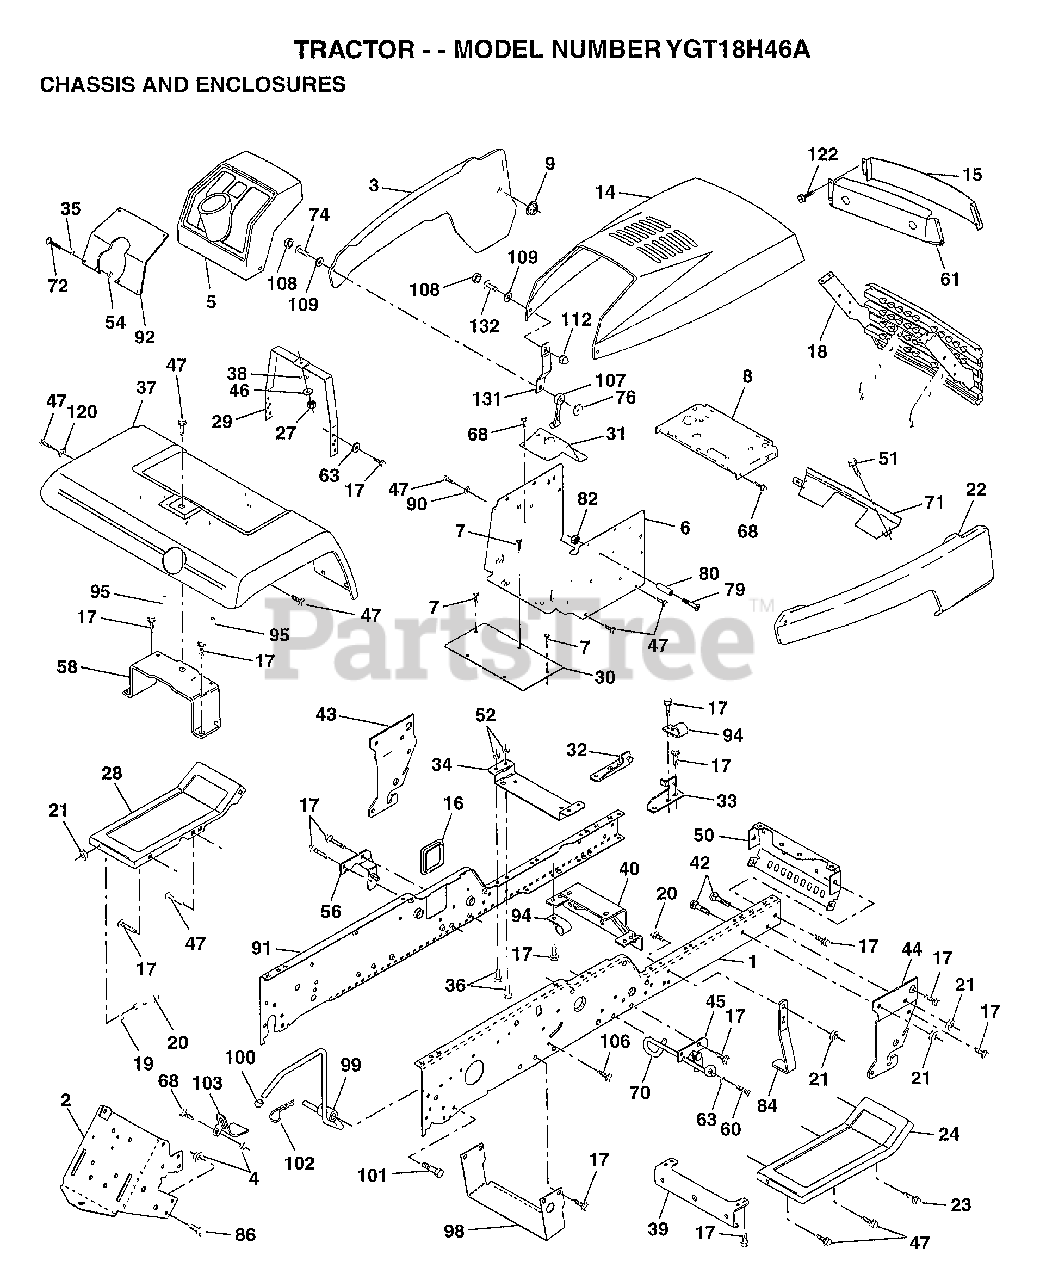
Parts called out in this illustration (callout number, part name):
1	"RAIL,FRAME RH"
2	DRAWBAR GT
3	"PANEL ASM-SIDE,LH"
4	NUT.7/16
5	DASHBOARD BLACK
6	DASH LOWER
7	SCREW
8	SUPPORT.DASH.BTRY
9	PAL NUT LT
14	"HOOD, YARD PRO"
15	LENS.BAR.CLEAR
16	COVER ACCESS
17	SCREW
19	WASHER
20	BOLT
22	"PANEL ASM SIDE,RH"
23	SCREW GTV
24	FOOTREST.RH.LT/GT
28	FOOTREST PNT LH
29	DASH.SUPT.YP/HUSQ
30	SADDLE.HYDRO.95
31	BRAKET.SUPT.STEER
32	BRACKET ASM FRAME
33	BRACKET ASM FRAME
34	BRACKET.ENG.SUPT.
35	WASHER
36	BOLT
37	"FENDER WS,FTK"
38	LOCKWASHER
39	BRACKET.AXLE.FRT.
40	"BRKT SUPPORT,AXLE"
43	BRACKET.SUS.FT.LH
44	BRACKET.SUS.FT.RH
45	BRACKET ASM., SUSP CHASSIS RH
46	WASHER PM
47	SCREW LT
50	"BRKT CHASSIS,FRNT"
51	SCREW CRT
56	BRACKET ASM., SUSP CHASSIS LH
58	BRKT.ASM.FENDER
60	SCREW
61	BEZEL.ASM.
63	WASHER
68	SCREW LT
70	GUIDE.BELT.MID.SP
72	SCREW
74	SCREW
76	WELDNUT
79	SCREW
80	SPACER LT
84	STOP.OVER.CENTER
86	BOLT
90	LOCKWASHER
91	"RAIL FRAME,LH"
92	"PLATE DASH,SLKSCR"
94	CLIP GTV
95	NUT-PUSH YT
98	BRACKET SKID CHAS
99	ROD BYPASS
101	SCREW LT
102	RETAINER M
103	LOCK BYPASS BRKT
107	HOOD LATCH T
108	SNAP CAP LT
109	WASHER LT
112	ACORN NUT RB
120	WASHER HYT
131	BKT.SPT.HOOD/PANL
132	SCREW.10-24X3/8.
